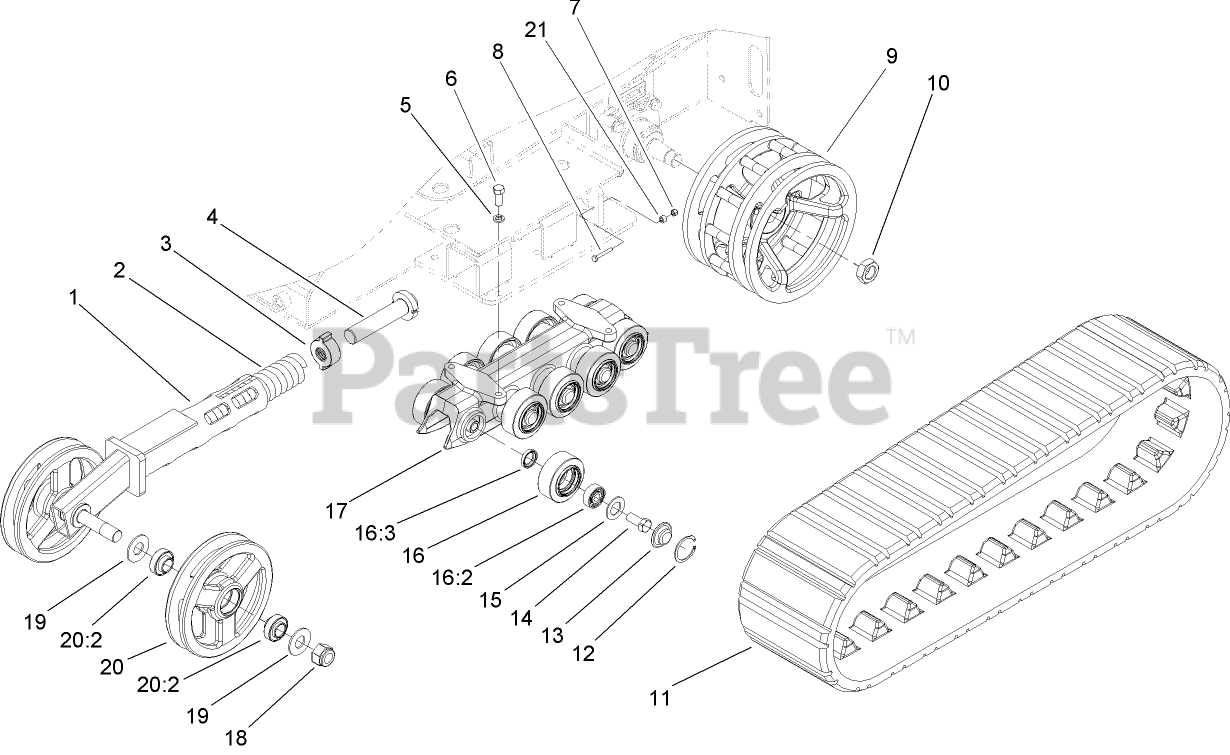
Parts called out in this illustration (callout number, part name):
1	TENSIONER ARM ASM
2	SPRING-COMPRESSION
3	BLOCK-TENSIONER
4	BOLT-TENSIONER
5	WASHER-LOCK
6	SCREW-HH
7	NUT-LOCK, NI
8	SCREW-HH
9	WHEEL-DRIVE
10	NUT-HEX
11	TRACK
12	RING-SNAP, INTERNAL
13	CAP-WHEEL, BEARING
14	SCREW-HH
15	Gasket-Bogie
16	Road Wheel ASM
16:2	BEARING
16:3	SEAL-OIL
17	GUIDE-TRACK
18	NUT-HEX, NI
19	Washer-Flat
20	Tensioner Wheel ASM
20:2	Bearing-Ball
21	SPACER
